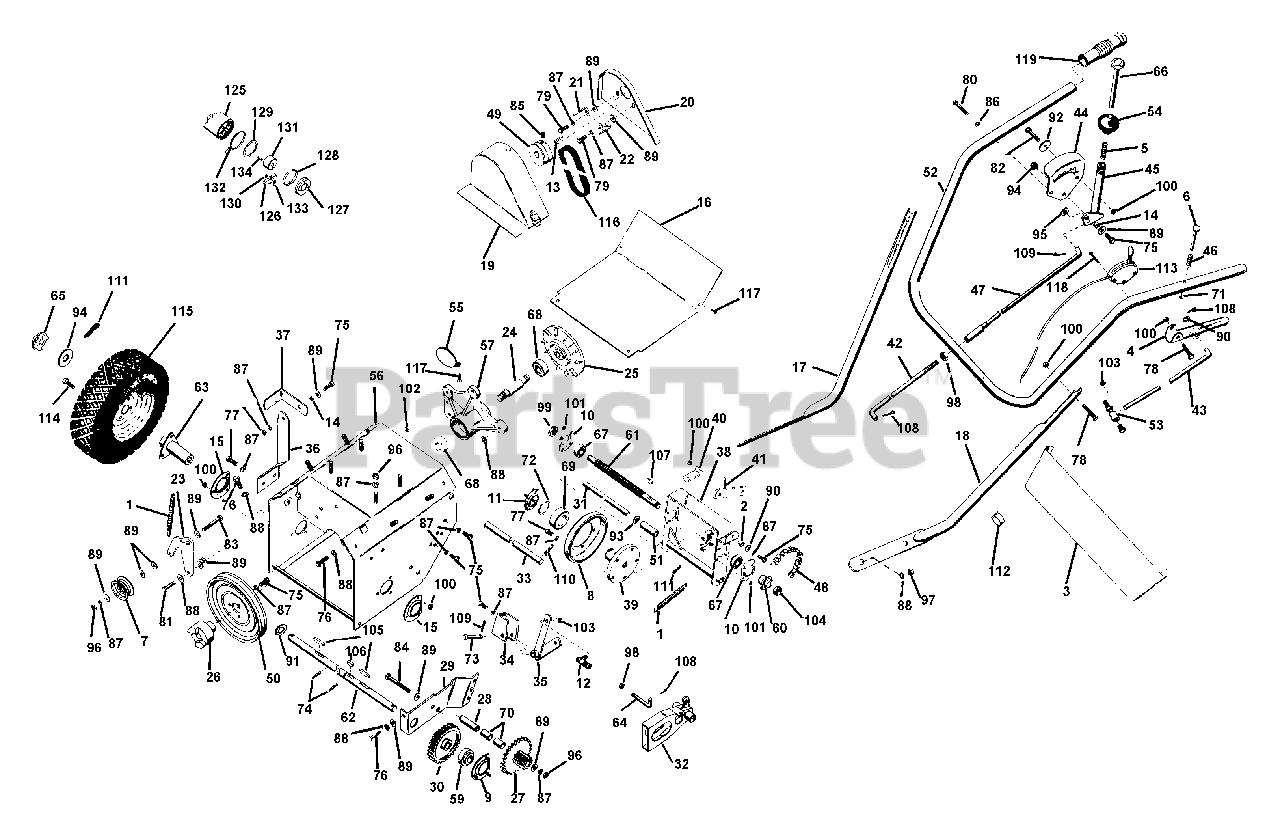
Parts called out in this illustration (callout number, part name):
1	SPRING
2	SPACER BUSHING .5 X .32 X .163
3	HANDLE BAR PANEL
4	CLUTCH HANDLE
5	SG-COMP ??X.44X?? WLD 10
6	CLUTCH LOCK PIN
8	FRICTION DISC
9	BEARING FLANGE
10	BEARING FLANGE
11	BEARING FLANGE
12	BALL JOINT
14	SPACER BUSHING .5 X .32 X .21
15	BEARING FLANGE
16	BOTTOM COV
17	R H LOWER HANDLE BAR
18	L H LOWER HANDLE BAR
19	OUTER BELT GUARD
20	INNER BELT GUARD
21	R H BELT FINGER
22	L H BELT FINGER
23	IDLER ARM
24	SPINDLE
25	DRIVE PLATE
26	JAW COUPLING
27	PINION & SPROCKET
28	PINION STUB SHAFT
29	SUPPORT BRACKET
30	SPUR GEAR, FELLOWS 35T .750 ID
31	BRACKET PIN
32	SLIDING FORK
33	FORK SHAFT
34	LEVER BRACKET
35	TRANSFER LEVER
36	CLTCH BRCKT
37	CLUTCH LEVER
38	DISC BRCKT
39	FRICTION DISC HUB
40	NEUTRAL CATCH
41	THROWOUT LEVER
42	LOWER SHIFT ROD
43	CLTCH ROD
44	SHIFT QUADRANT
45	SHIFT HANDLE
46	SPRING
47	SHIFT ROD
48	ROLLER CHAIN
49	ENGINE SHEAVE
52	UPPER HANDLE BAR
53	BALL JOINT
54	SHIFT BALL
56	TRACTOR FRAME
57	BEARING HOUSING
58	6 HP CARB COVER
59	BRNG
60	9 TOOTH SPROCKET
61	SPLINED SHFT
62	AXLE SHAFT
63	WHEEL HUB
64	CONNECTING LINK
65	HUB CAP
66	SHIFT RELEASE HANDLE
67	BRG-BALL .625X1.375X.44
68	BRG-BALL .750X1.750X.50
69	BRG-BALL 1.25X2.18X.63
70	BSHG-FLG .625X.750X.500X.875BR
71	RG-RTNG-EXT .250X.031
72	RG-RTNG-EXT 1.250X.050
73	CLEVIS PIN
74	PIN-ROLL .250X1.25
75	BLT-HEX .31-18X.63 PL GR 2
76	BLT-HEX .31-18X.63 PL GR 2
77	BLT-HEX .31-18X1.00 PL GR 2
78	BLT-HEX .38-16X1.25 PL GR 2
79	BLT-HEX .38-16X1.25 PL GR 2
80	BLT-HEX .38-16X1.25 PL GR 2
81	BLT-HEX .38-16X1.50 PL GR2
82	BLT-HEX .44-14X1.25 PL GR2
83	BLT-HEX .44-14X1.25 PL GR2
84	BLT-HEX .44-14X1.25 PL GR2
85	SCR-SET .38-16X.50 SKHCUP OH
86	WSHR-LK .250X.077 HVY PL
87	WSHR-LK .312X.097 PL HVY
88	WSHR-LK .375X.115 HVY PL
89	WSHR-FL-STL .38X.875X.083 PL
90	BRG-CUP1.980X.420
91	WSHR-FL-STL .531X1.062X.095 PL
92	WSHR-FL-STL .531X1.062X.095 PL
93	BRG-NEEDLE .625X.812X.50
94	WSHR-FL-STL .755X2.000X.125
95	WSHR-FL-STL.406X.812X.065PL
96	NUT-JAM .375-16 PL
97	NUT-JAM .375-16 PL
98	NUT-HEX .312-24 PL
99	NUT-LK-CTR .625-18 PL
100	NUT-LK-CTR .250-20 PL
101	NUT-LK TOP 10-24 PL
102	NUT-LK .312-18 GR A PL
103	NUT-LK-CTR .312-24 PL
104	NUT-LK-CTR .50-20 PL
105	KEY-WDRF .188X.875X.375 SAE11
106	KEY-WDRF .188X.875X.375 SAE11
107	KEY-WDRF .188X.875X.375 SAE11
108	PIN-COTR .09X.75 PL
109	PIN-COTR .12X1.0 PL
110	PIN-COTR .09X.75 PL
111	PIN-COTR .09X.75 PL
112	THROTTLE CONTROL
113	THROTTLE CONTROL
114	BRG-CUP 2.441X.562
115	T/WHL ASSY
115	TIRE 4.10/3.50X6 2PLY
115	WHL 6 IN O.D.
116	V-BELT, SAE 380-RAW EDGE
117	SCR-TAP 10-12X.50 CRPH PL A
118	SCR-TAP 10-16X1.0 SLHP PL AB
119	GRIP
120	DISCHARGE CAUTION LABEL
121	DISCHARGE CAUTION LABEL
122	DISCHARGE CAUTION LABEL
123	DISCHARGE CAUTION LABEL
124	DISCHARGE CAUTION LABEL
125	RATCHET WHEEL HUB
128	FRICTION SPRING
129	RETAIN WASH
130	WAVE WASHER .406X.750X.063FH
131	PAWL HUB
132	O-RING 3.85X4.27X.210
133	PIN-ROLL .188X.88
134	PIN-GRV .375X1.00 TP C
